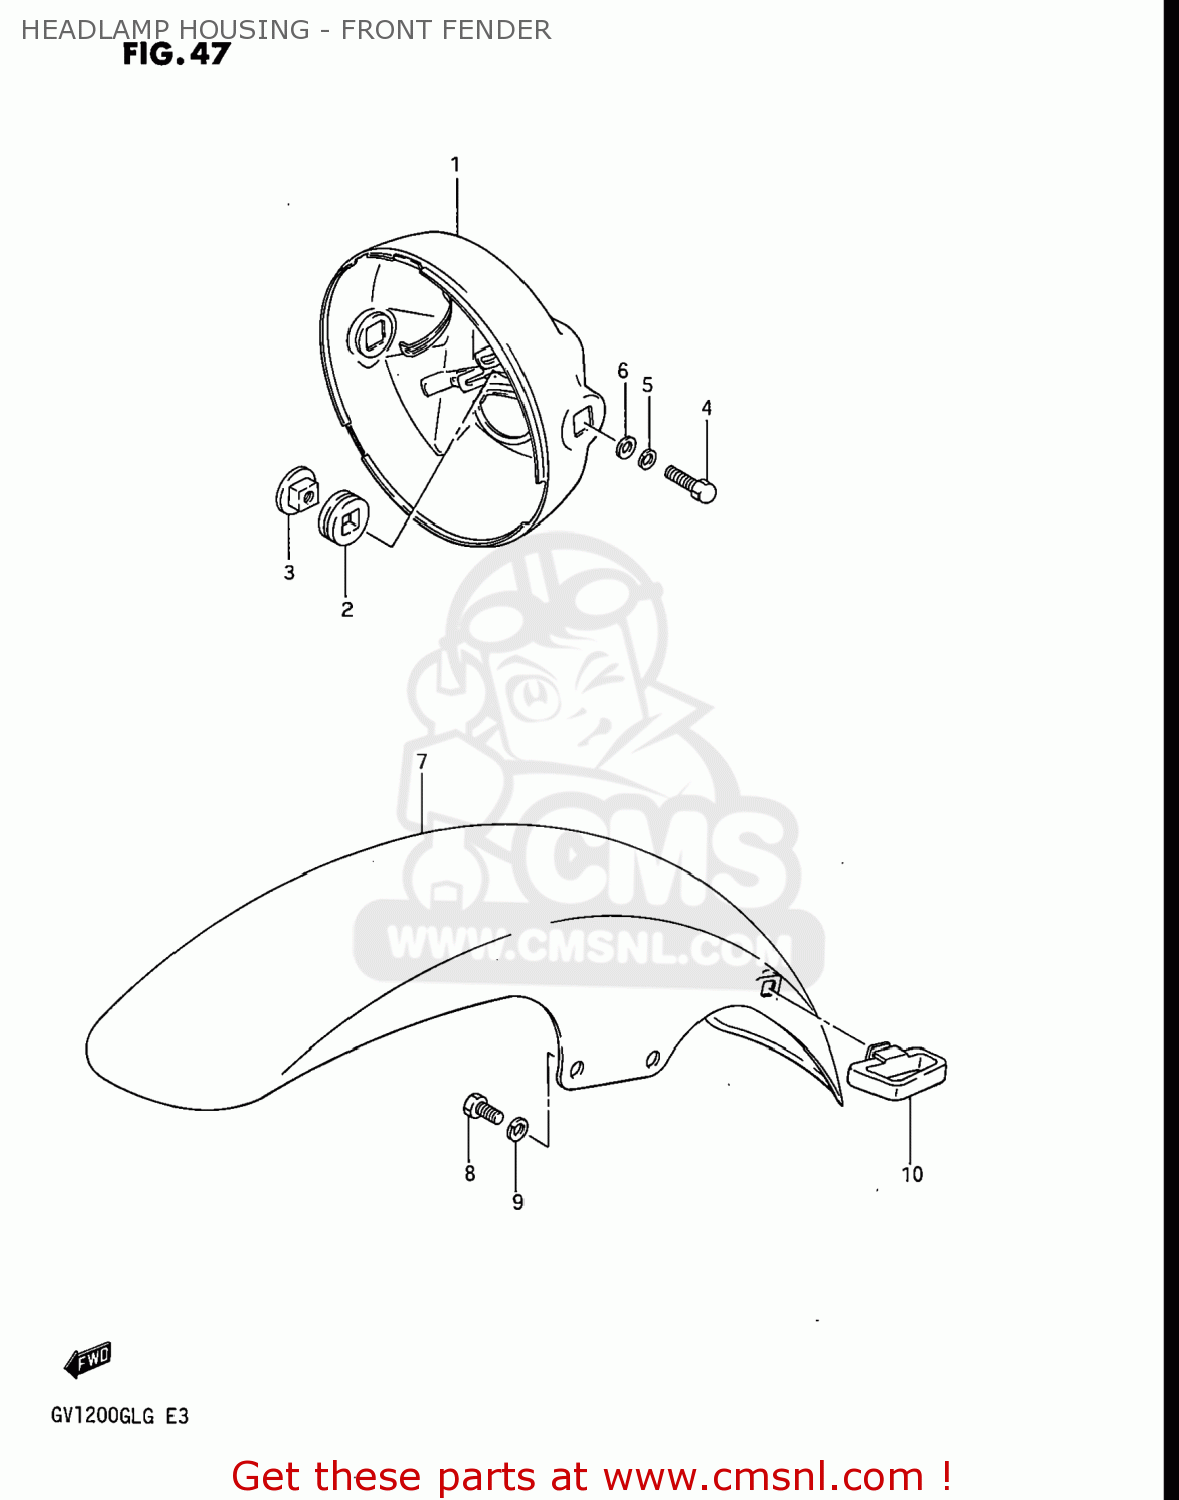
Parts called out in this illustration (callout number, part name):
1	HOUSING,HEADLAMP (COWLING)
2	CUSHION,HEADLAMP HOUSING
3	SPACER,HEADLAMP HOUSING
4	BOLT
5	LOCK WASHER
6	WASHER
7	FENDER,FR
8	BOLT,8X16
9	LOCK WASHER
10	GUIDE,CABLE
